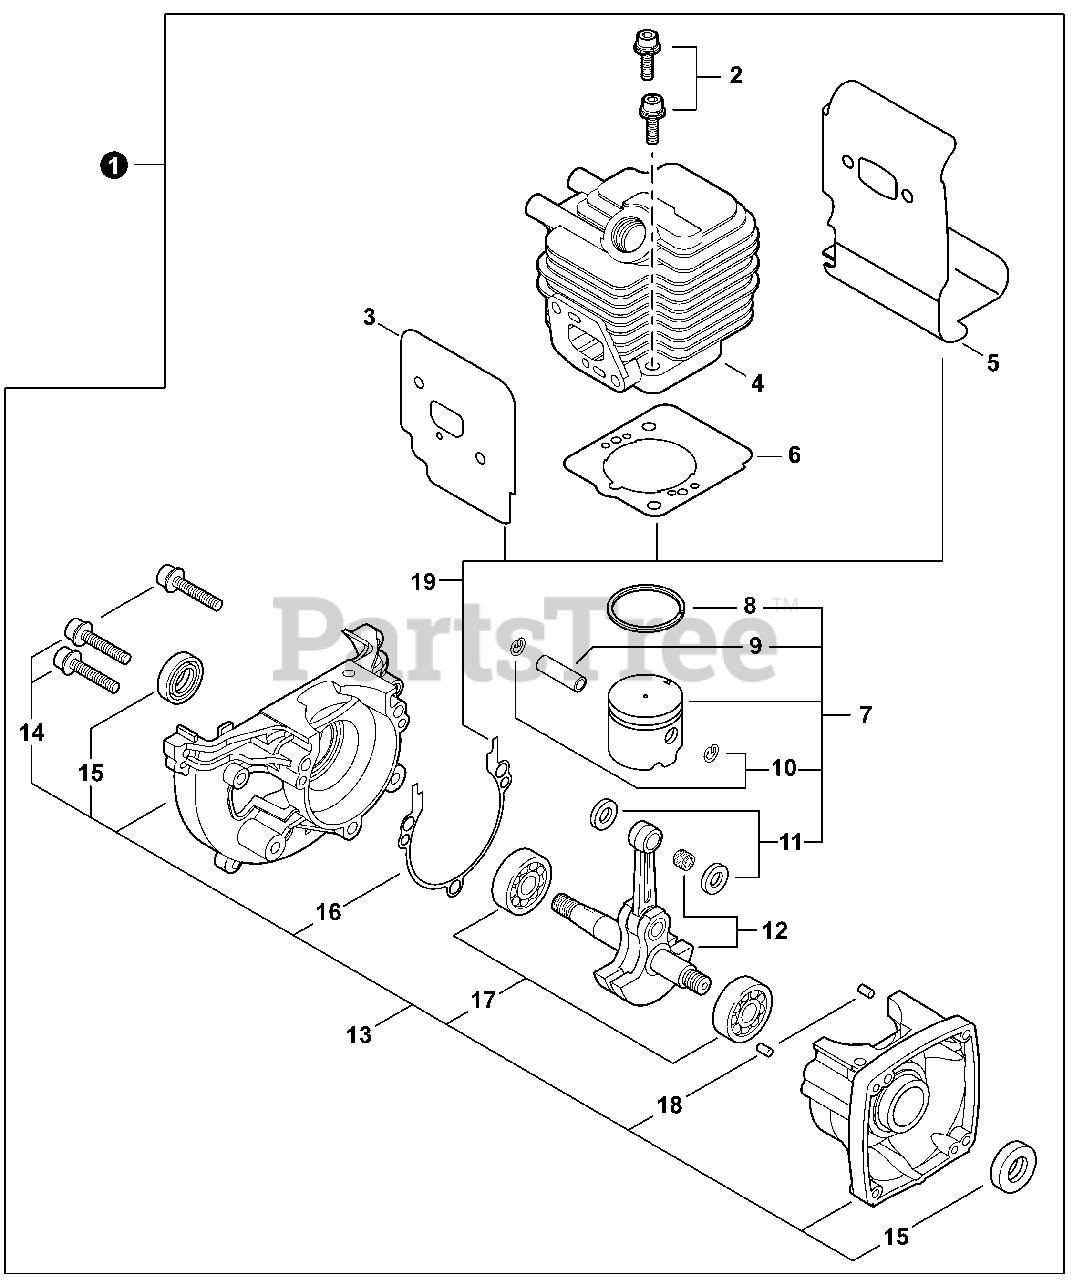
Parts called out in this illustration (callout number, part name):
1	SHORT BLOCK
2	BOLT 5×22
3	HEAT SHIELD, INTAKE
4	CYLINDER
5	HEAT SHIELD, EXHAUST
6	GASKET, CYLINDER
7	PISTON KIT
8	RING, PISTON
9	PIN, PISTON 8
10	RING, SNAP
11	WASHER, THRUST
12	CRANKSHAFT ASSY
13	CRANKCASE KIT
14	BOLT 5×28
15	SEAL, OIL 12
16	GASKET, CRANKCASE
17	BEARING, BALL - 6201 C3
18	PIN, LOCATING 4×8
19	GASKET KIT
